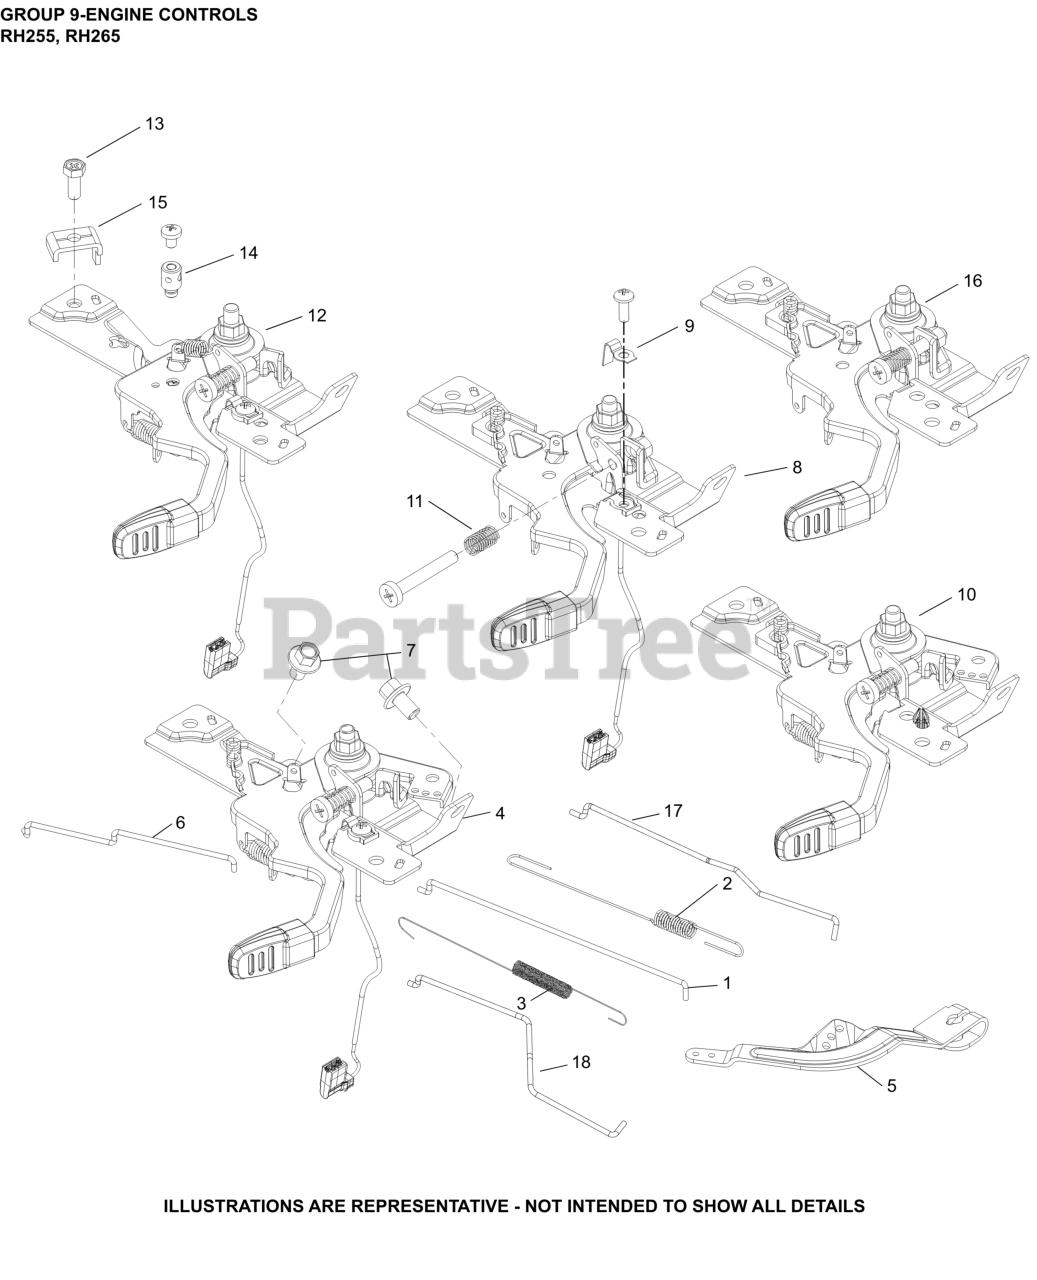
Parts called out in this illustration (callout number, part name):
1	LINKAGE, GOVERNOR-USE 18 079 05-S
2	SPRING, GOVERNOR
3	SPRING, LINKAGE
5	LEVER, GOVERNOR
7	SCREW, FLG M6X1.0X10
8	FIXED SPEED CONTROL ASSEMBLY
9	PLATE, KILL SWITCH
11	SPRING, COMPRESSION
